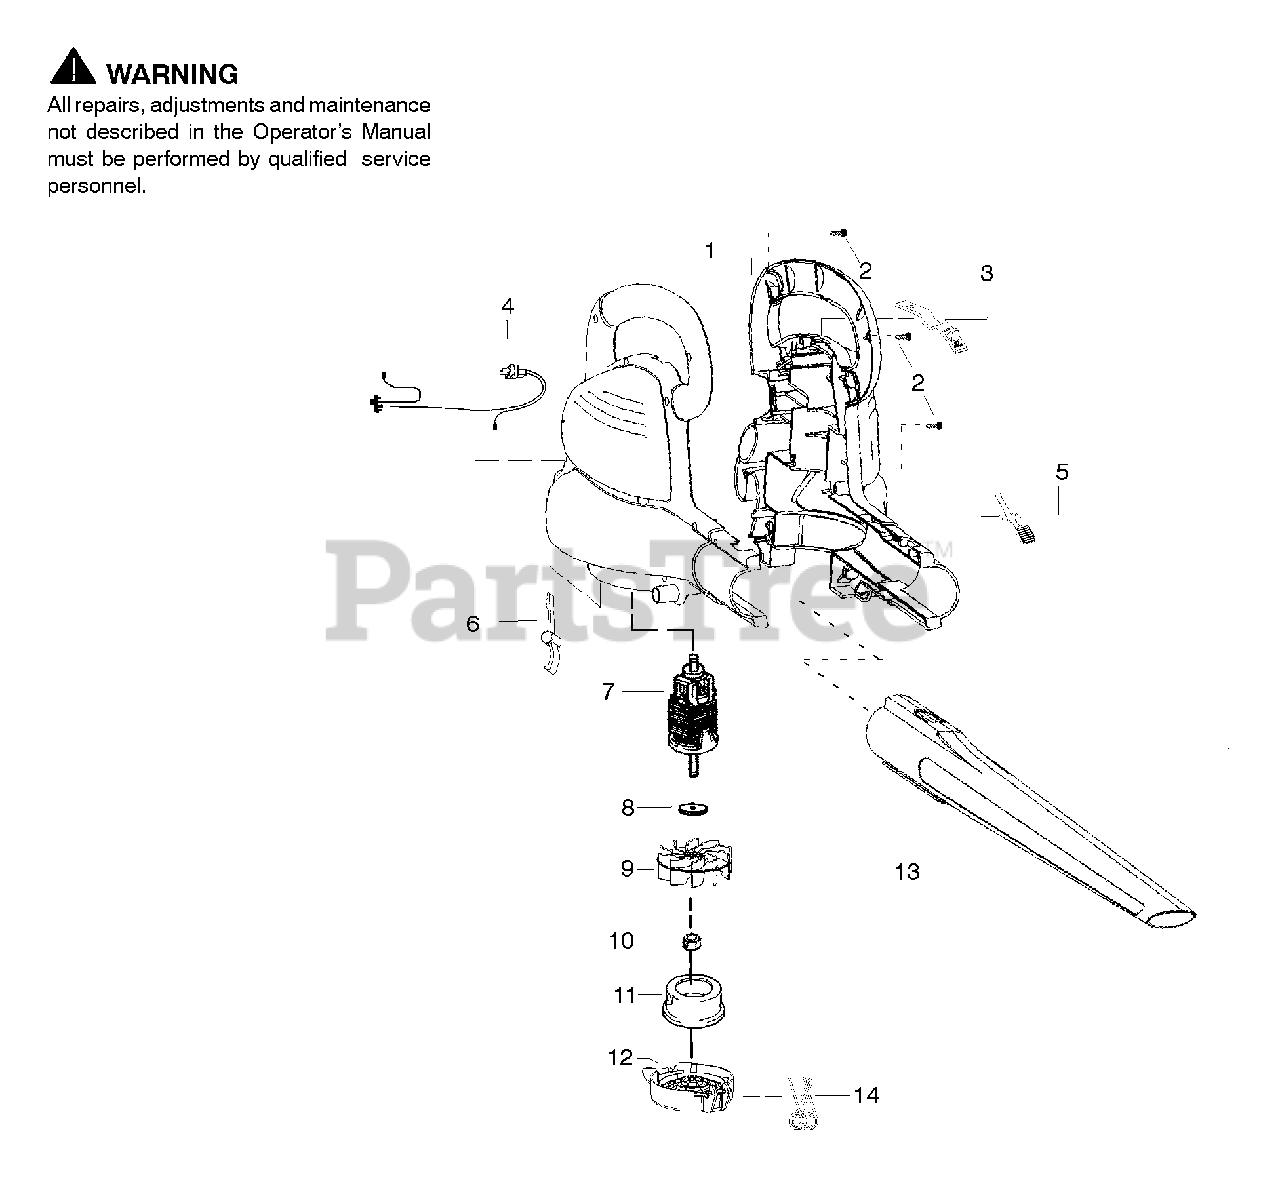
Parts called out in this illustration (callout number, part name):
1	Housing Set
3	Cover - Switch
4	Assy. Wiring Harness
5	Button - Tube Latch
6	Button - Door Latch
7	Assy. Motor
9	Impeller
10	Nut - Impeller
11	Restrictor - Inlet
12	Door - Vacuum Inlet
13	Tube - Blower
14	Spring - Door
